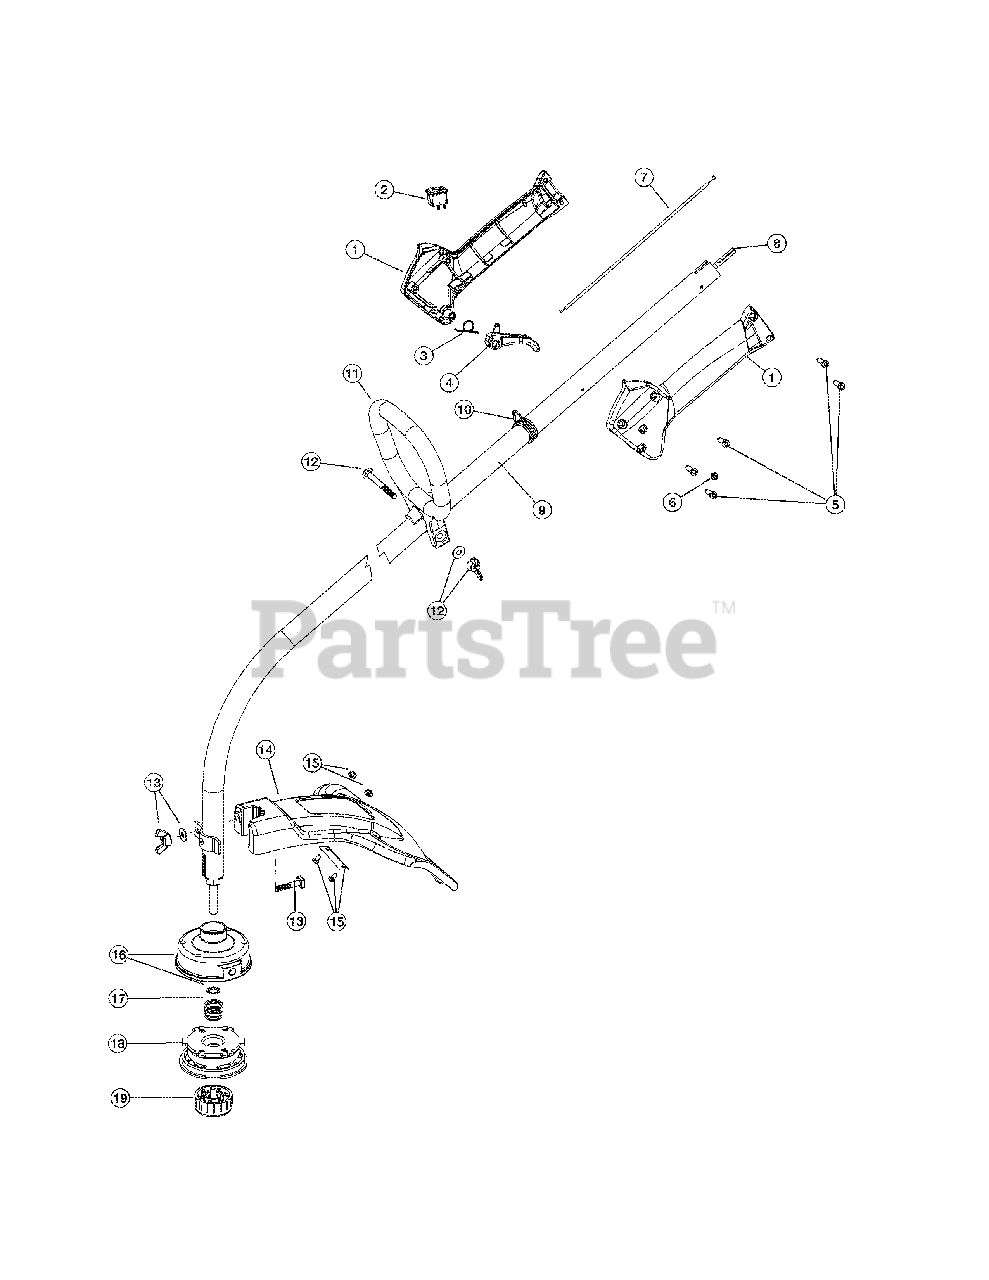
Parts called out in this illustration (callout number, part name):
1	Throttle Housing Assembly (includes 2-4)
3	Throttle Trigger Spring
4	Throttle Trigger
5	Throttle Housing Screws
6	Anti-Rotation Screw
7	Throttle Cable
8	Flexible Drive Shaft
9	Drive Shaft Housing Assembly (includes 8)
10	Harness Clip
11	D-Handle Assembly (includes 12)
12	D-Handle Hardware
13	Guard Mounting Hardware
14	Guard (includes 15)
15	Blade Assembly
16	Outer Reel w/Retainer
18	Inner Reel
